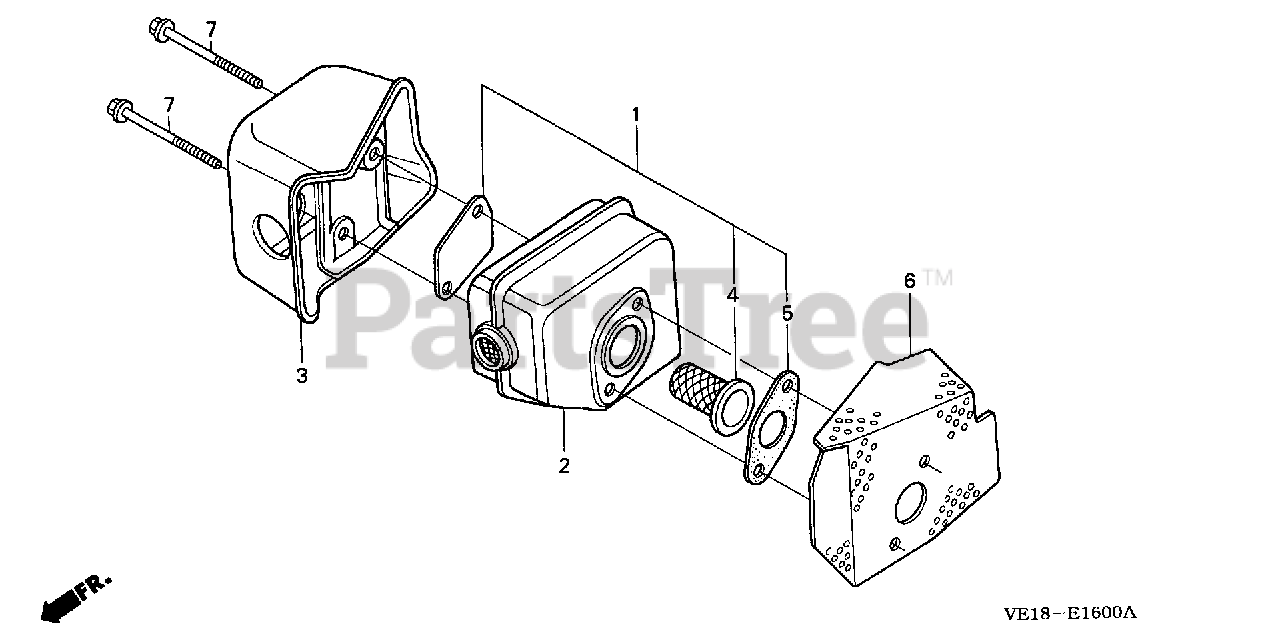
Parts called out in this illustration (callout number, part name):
1	ARRESTER KIT, SPARK
2	MUFFLER
3	PROTECTOR, MUFFLER
4	ARRESTER KIT, SPARK
5	GASKET, MUFFLER
6	GASKET, MUFFLER
7	BOLT, FLANGE (6X85)
